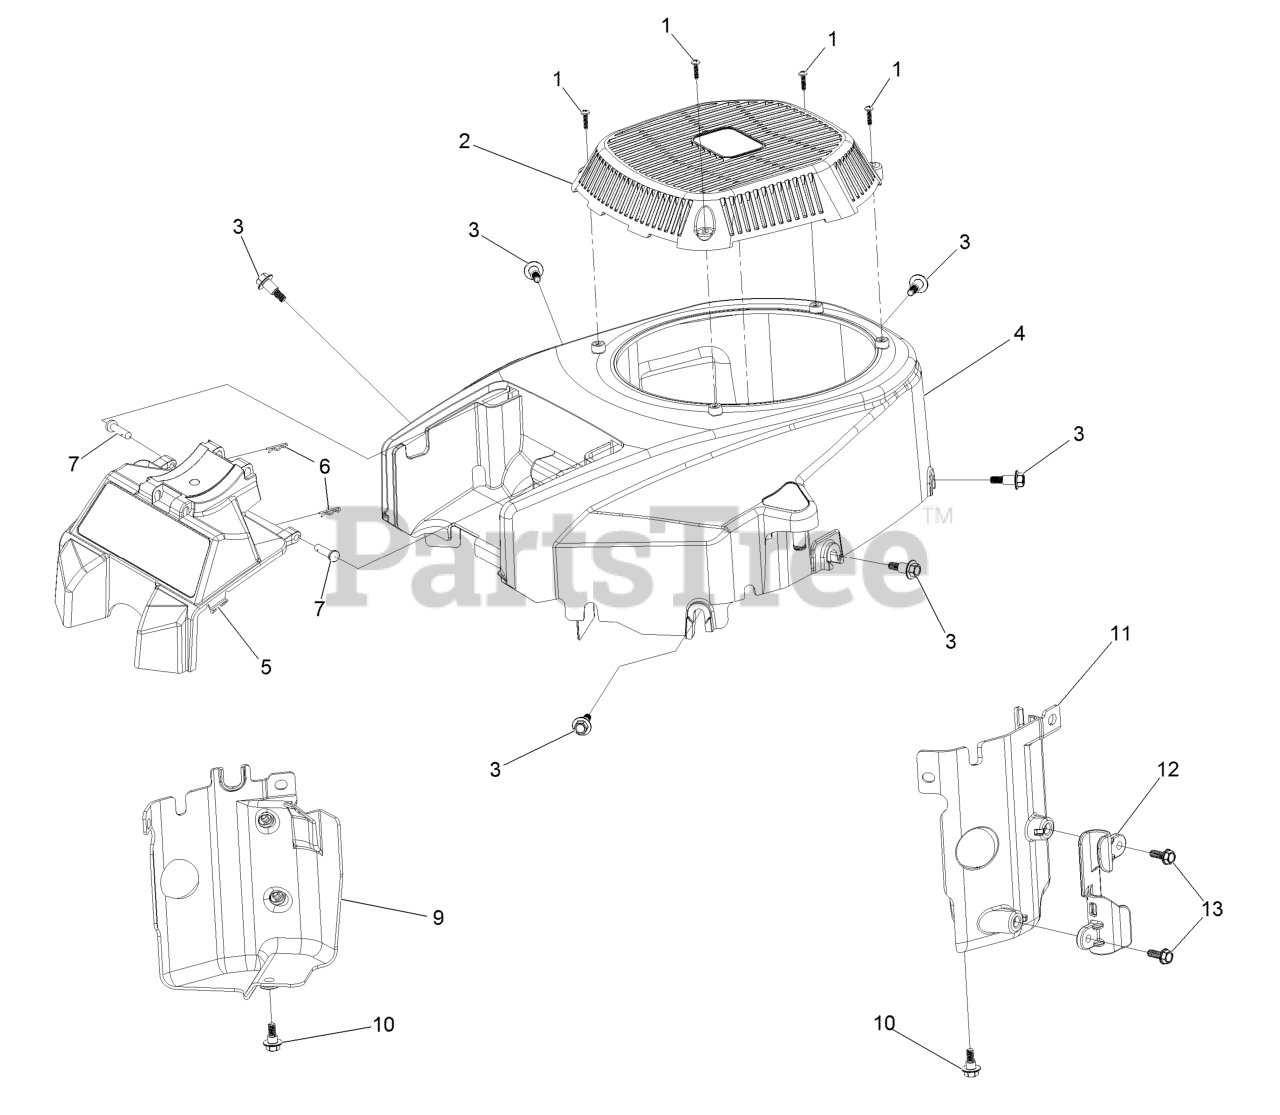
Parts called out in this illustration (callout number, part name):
1	Screw-PPH, Plastic
2	Cover-Fan
3	Screw-Shoulder, HWH
4	Shroud-Engine
5	Support-Filter
6	Pin-Hair
9	Baffle-Air, Left
10	Screw-Shoulder, HHF
11	Baffle-Air, Right
12	Cleat-Hose
13	Screw-HHF
